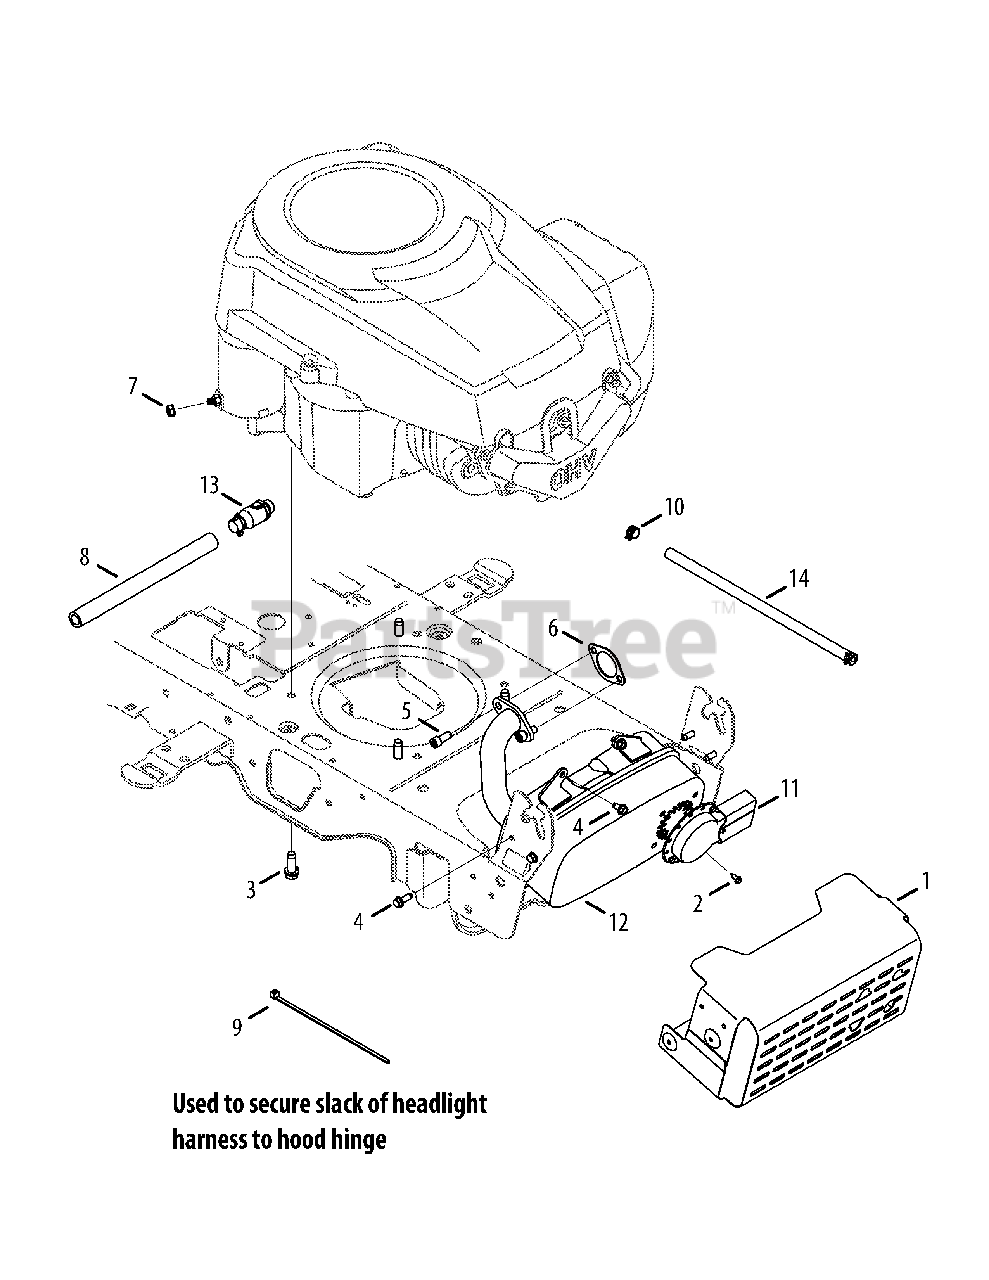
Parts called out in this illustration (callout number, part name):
1	Muffler Shield Assembly
2	Screw, Indented Washer, #8-18:0.500
3	Taptite Screw, 3/8-16:1.000
4	Taptite Screw, 1/4-20:0.750, Briggs
5	Socket Head Screw, 5/16-18:.750
6	Gasket, Exhaust, Briggs
7	Sems Nut, 1/4-20
8	Extension Hose, Oil Drain
9	Cable Tie, 3/16 x .05 x 7.4
10	Hose Clamp, .490 DIA.
11	Long Muffler Deflector
12	Muffler, Briggs
